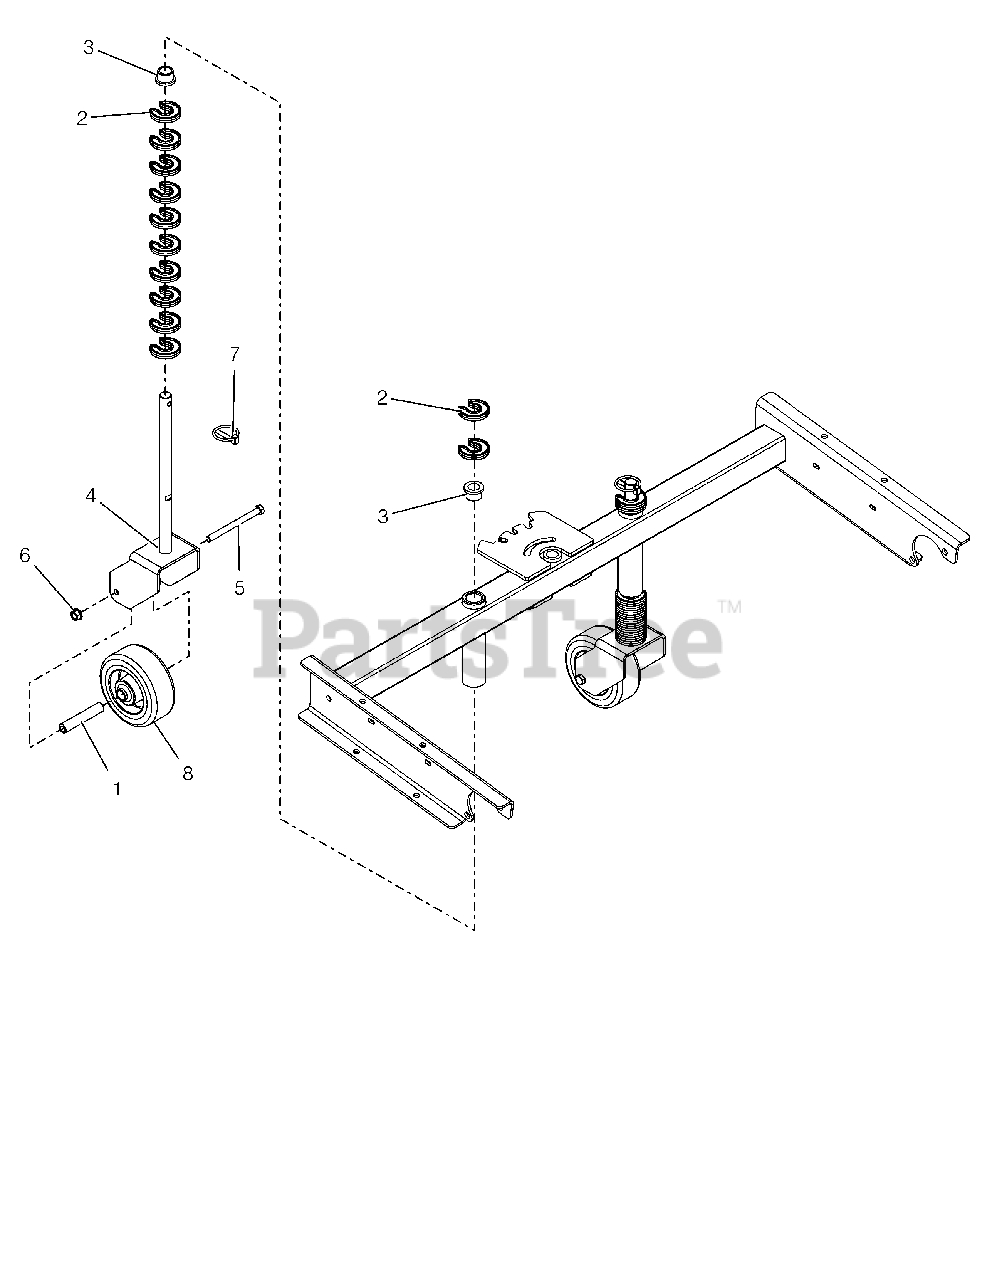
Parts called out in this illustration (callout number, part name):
1	SPACER, CASTER WHEEL
2	CLIP-HOC FIXED
3	BUSHING, FLANGE .75X.75X1.0
4	FORK, CASTER
5	@BLT-HEX .38-16X4.50 GR5 YWZC
6	@NUT-LK-TOP-FLG .38-16 YWZC
7	PIN, 1/4X1-9/16 LYNCH
8	WHEEL, CASTER - 5"OD
